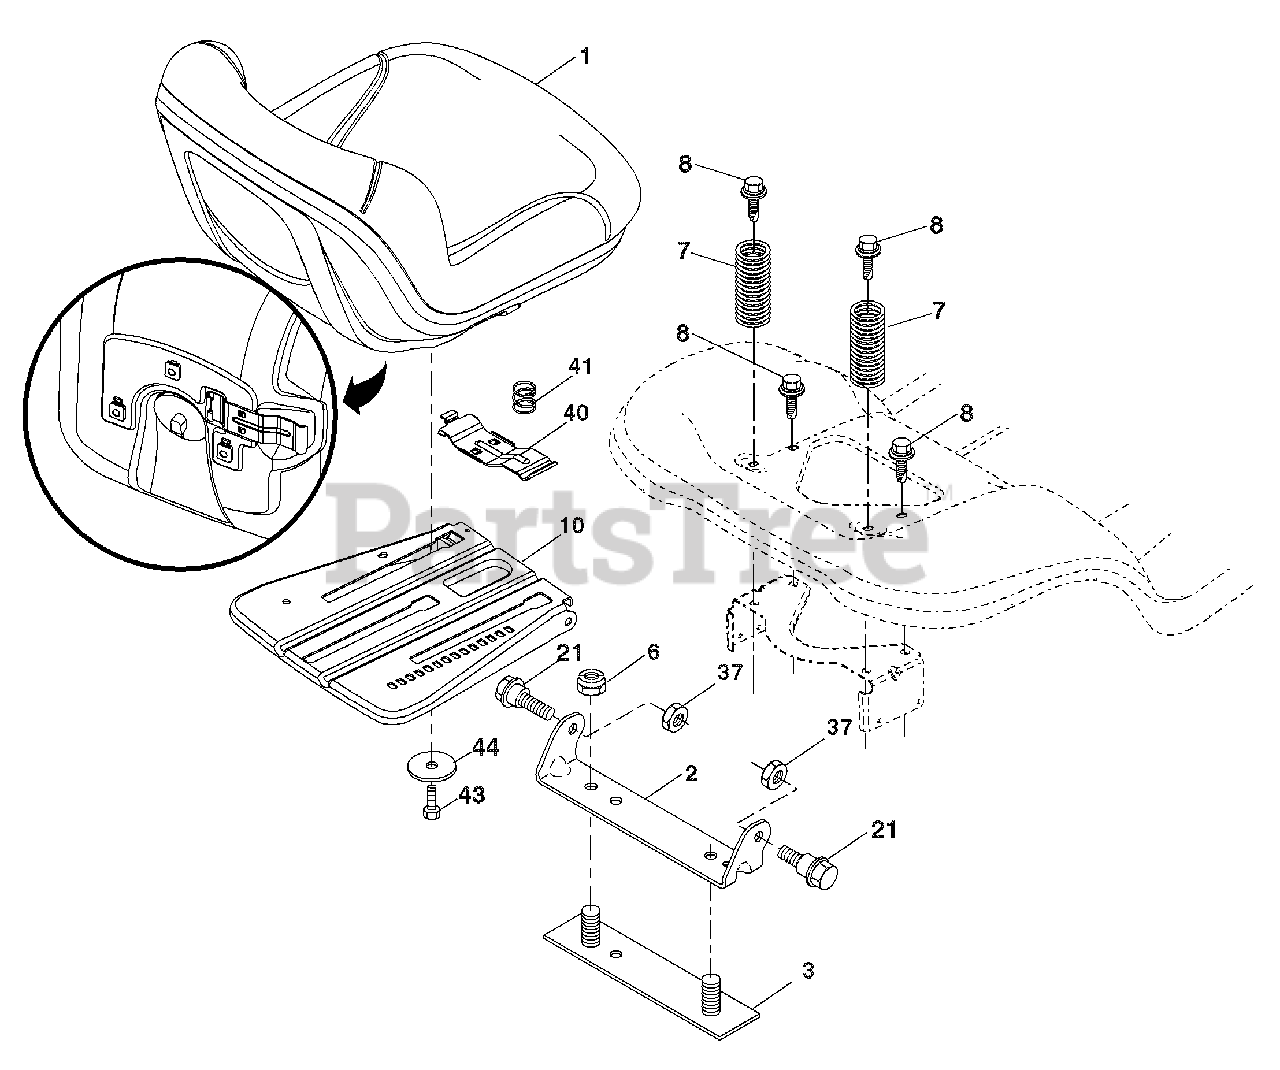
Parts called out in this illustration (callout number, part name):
1	Seat
2	Bracket Pivot Fender
3	Strap, Asm Fender
6	Nut, Lock W/Ins. 3/8-16 unc
7	Spring, Seat Cprsn
8	Bolt 5/16-18 uncx 3/4 w/Sems
10	Pan, Seat
21	Bolt, Shoulder 5/16-18
37	Nut, Lock 5/16-18 unc
40	Handle Slide Seat
41	Spring Latch Seat
43	Bolt Fin Hex 3/8-16 unc x 3/4
44	Washer 13/32 x 2-3/8 x 12 Ga.
